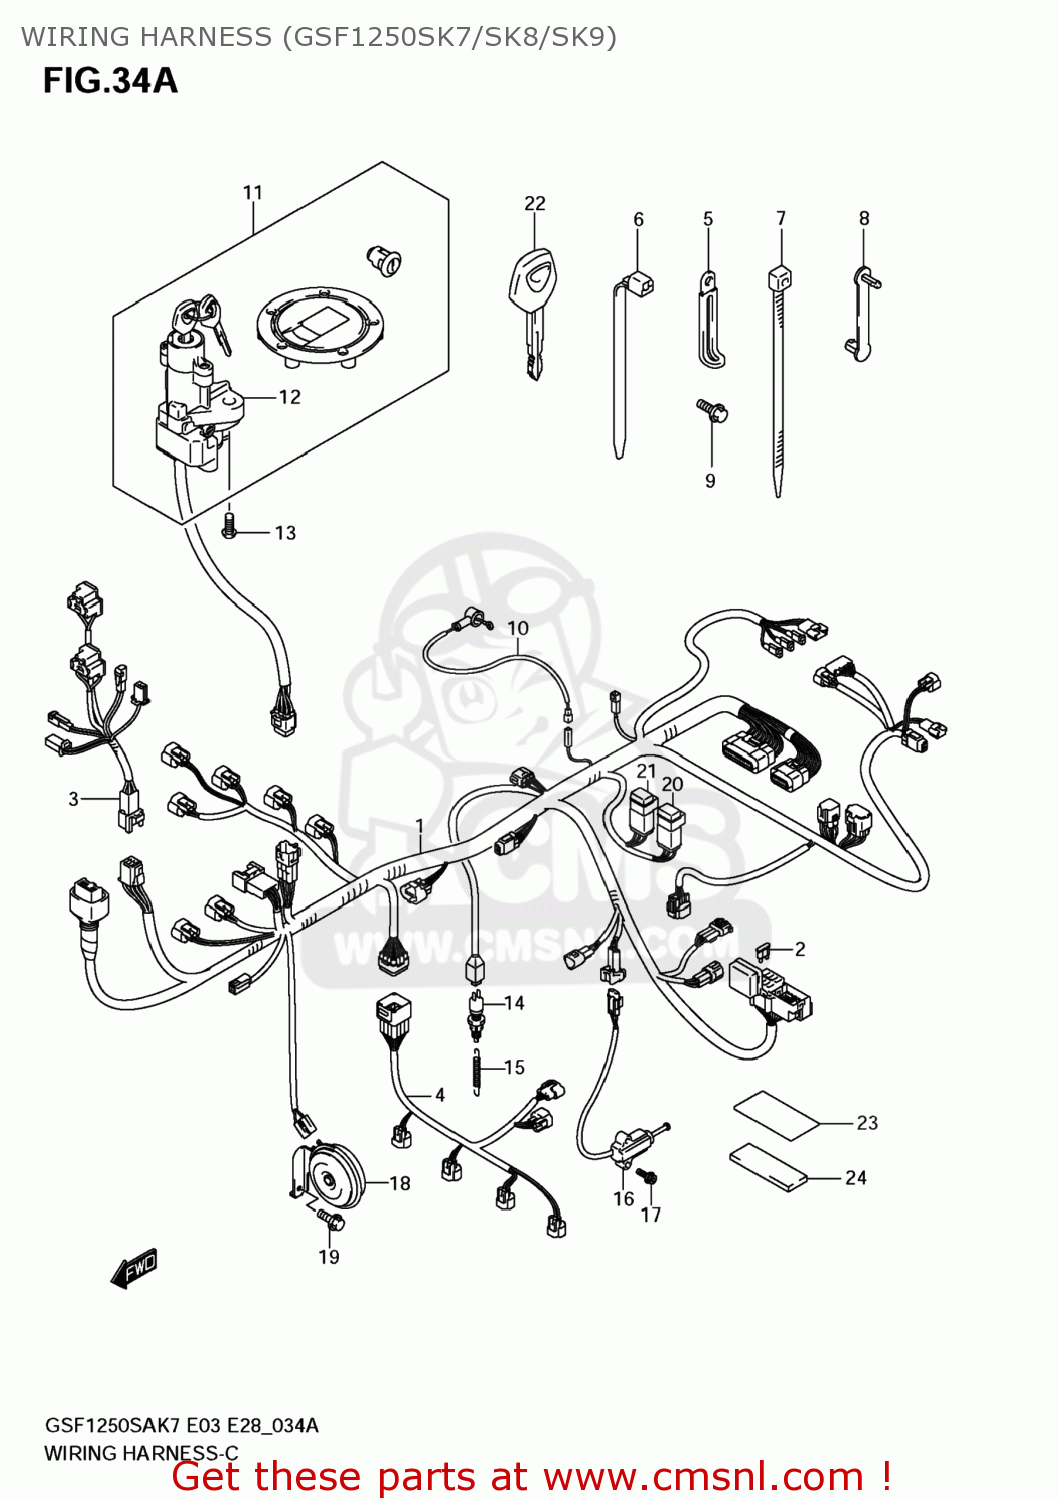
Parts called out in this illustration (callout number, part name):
1	HARNESS,WIRING NO.1
2	FUSE(10A)
3	HARNESS,WIRING NO.2
4	WIRE,INJECTOR LEAD
5	CLAMP(L:45)
6	CLAMP(L:95)
7	CLAMP(L:145)
8	CLAMP(L:33)
9	BOLT
10	WIRE,OIL PRESSURE SWITCH LEAD
11	LOCK SET
12	LOCK ASSY,STEE
13	BOLT(8X20)
14	SWITCH ASSY,STOP LAMP
15	SPRING
16	SWITCH ASSY,SIDE STAND
17	BOLT
18	HORN ASSY
19	BOLT
20	RELAY ASSY
21	RELAY ASSY
22	KEY,BLANK
23	TAPE,RR FENDER
24	PROTECTOR(20X90)X2
